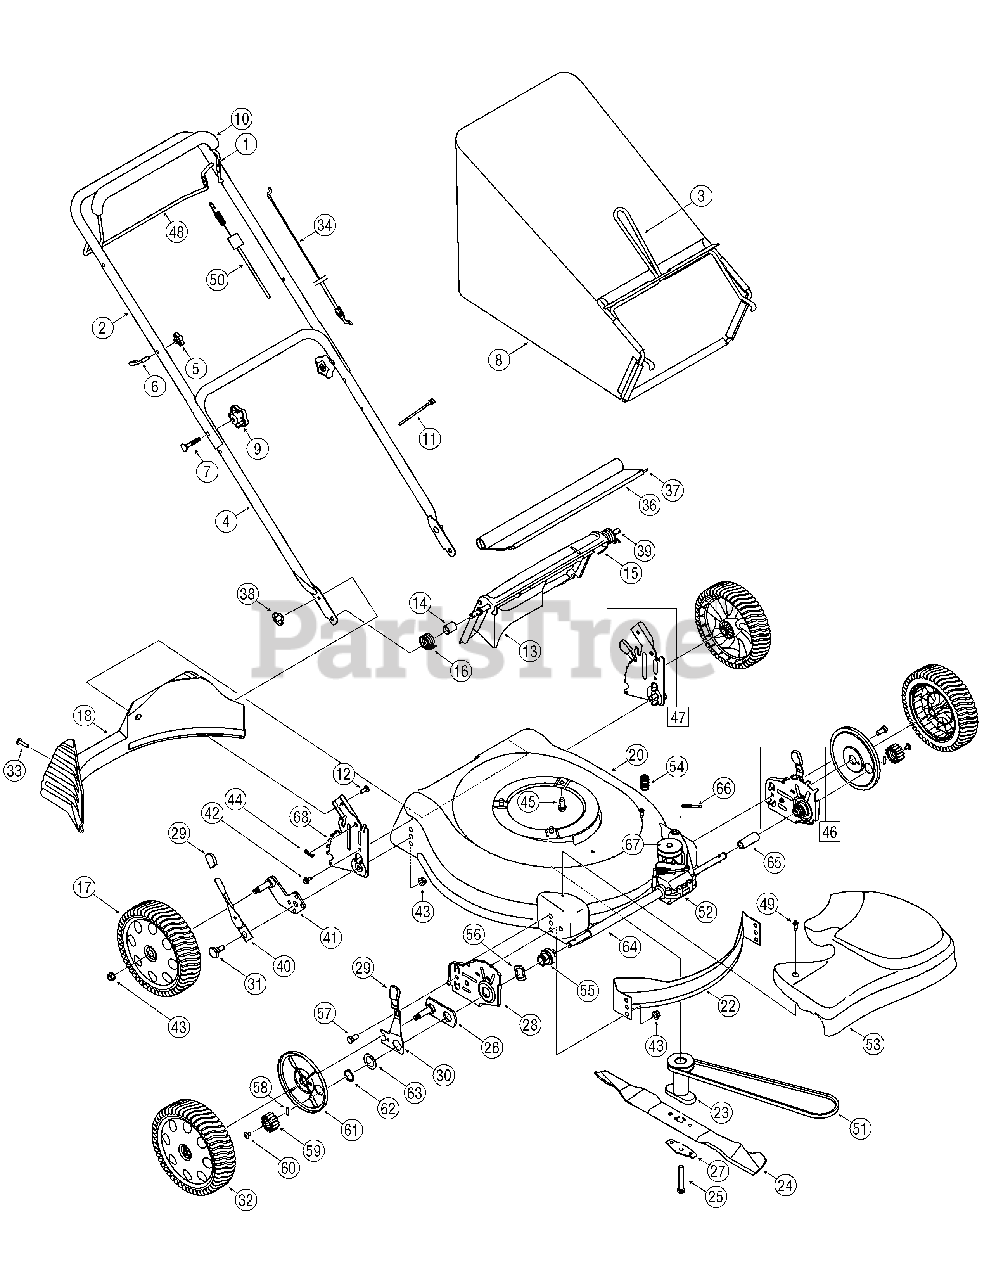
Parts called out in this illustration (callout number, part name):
6	Rope Guide
7	Carriage Bolt ,5/16-18 x 2
8	Grass Bag Assembly
9	Star Knob 5/16-18
10	Deluxe Bale Cover
11	Cable Tie
12	Carriage Bolt ,1/4-20
13	Rear Discharge Door
14	Spacer
15	Torsion Spring - LH
16	Torsion Spring - RH
17	Rear Wheel, 8" x 2.125"
18	Rear Baffle
22	Front Baffle
23	Blade Adapter w/Pulley
24	21" Standard Cut Blade
25	Hex Bolt , 3/8-24 x 2.5
26	Pivot Plate Assembly
27	Blade Bell Support
28	Height Adjustment Plate - RH
28	Height Adjustment Plate - LH
29	Adjustment Lever Knob
30	Front Lever - RH
30	Front Lever - LH
31	Shoulder Screw
32	Front Wheel, 8" x 2.125"
33	Screw, 1/4-15 x 1.250
34	Control Cable - 40.75"
36	Trailshield
37	Trailshield Wire
38	Wing Nut, 1/4-20
39	Rear Door Pivot Rod
40	Spring Lever
41	Pivot Arm Assembly - RH
41	Pivot Arm Assembly - LH
43	Flange Lock Nut, 3/8-16
44	Hairpin Clip
45	TT Sems Screw, 3/8-16 x 1.00
46	Ht. Adj. Assy. Front - LH
46	Ht. Adj. Assy. Front - RH
47	Rear Handle Bracket Assy. - LH
47	Rear Handle Bracket Assy. - RH
48	Lower Bail Handle
49	Shoulder Screw
50	Drive Cable 51"
51	V-Belt
52	Transmission Assembly
53	Front Drive Cover
54	Belt Tension Spring
55	Bearing Assembly
56	Wave Washer
57	Hex Screw
58	Dowel Pin
59	Gear, 14T - RH
59	Gear, 14T - LH
60	Screw 1/4-20
61	Wheel Dust Cap
62	Snap Ring
63	Washer, 1.5" OD
64	Sleeve Spacer - LH
65	Sleeve Spacer - RH
66	Roll Pin
67	Input Pulley
68	Handle Bracket - RH
68	Handle Bracket - LH
